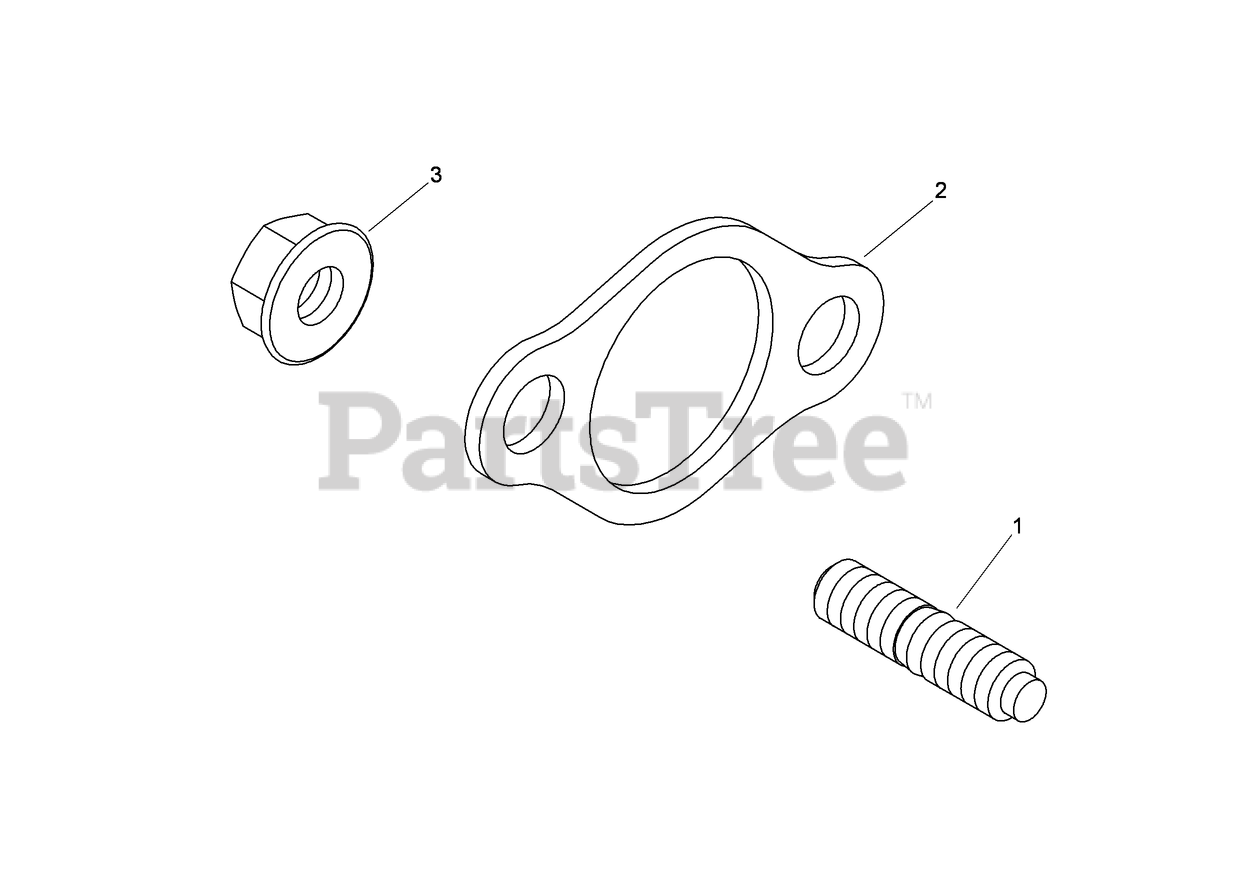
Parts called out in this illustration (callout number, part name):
1	STUD (M8X1.25X33)
2	GASKET-EXHAUST
3	NUT-FLANGE (M8X1.25)
